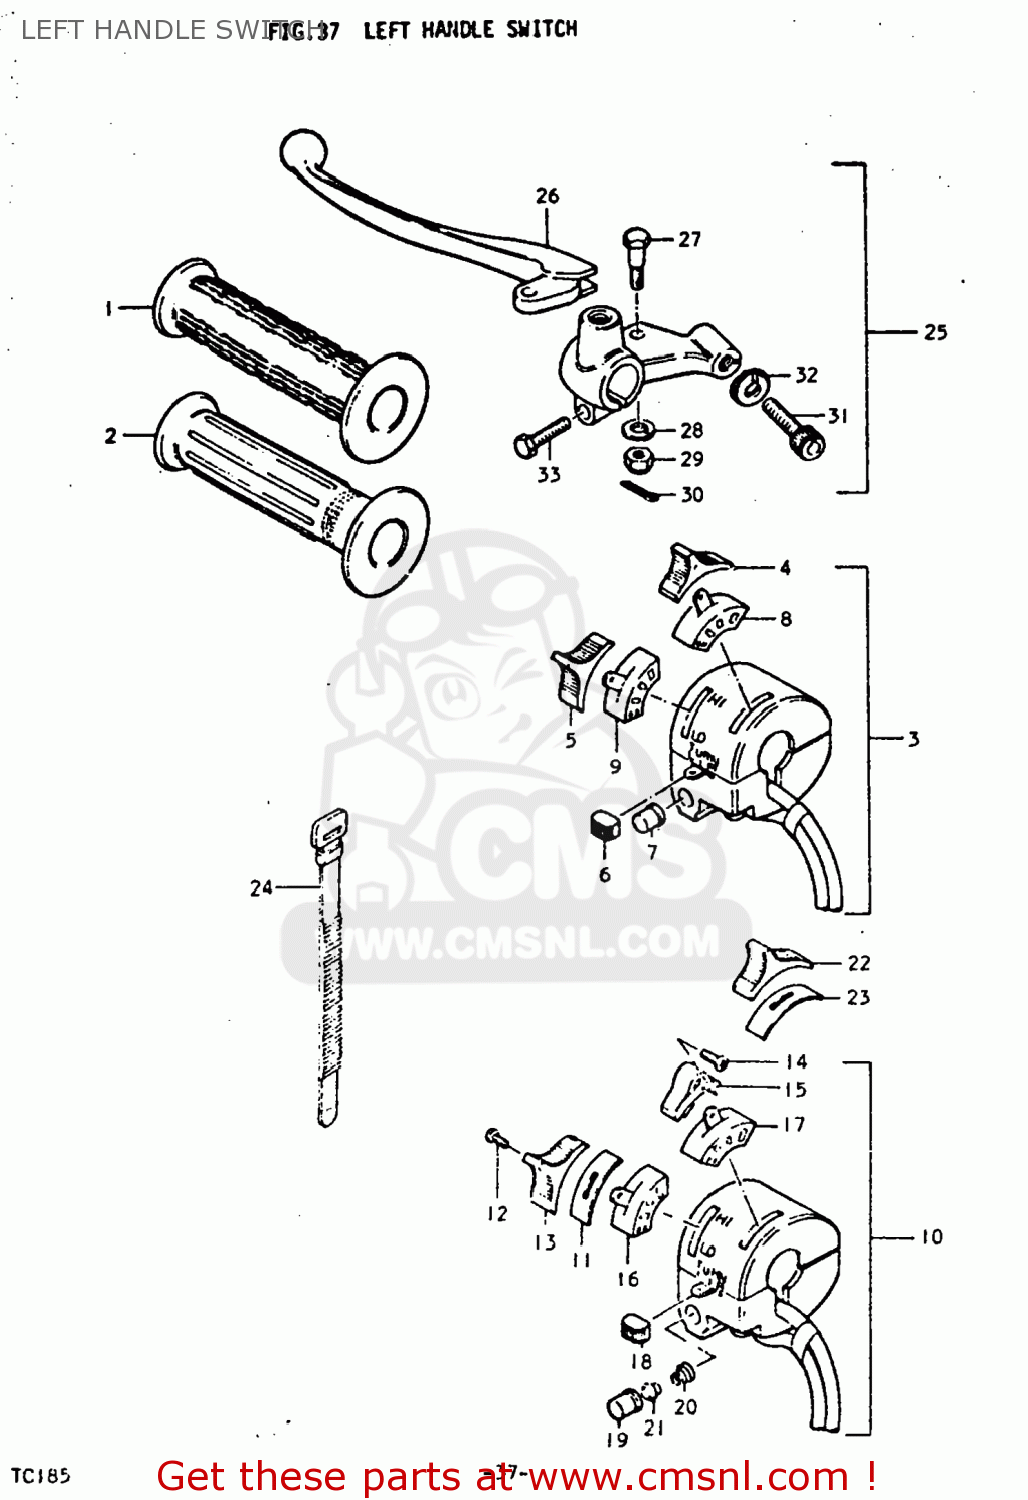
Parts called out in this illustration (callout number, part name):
1	GRIP
2	GRIP,L
3	SWITCH ASSEMBLY,HANDLE
4	KNOB,HANDLE SWITCH
5	KNOB,HANDLE SWITCH,UPPER
6	KNOB,HANDLE SWITCH
7	BUTTON, HORN
8	BLOCK, LIGHTING SWITCH SILDIN (L,ML,M)
9	SLIDING BLOCK, DIMMER SWITCH
10	SWITCH ASSEMBLY,HANDLE,LEFT
11	PLATE,DIMMER KNOB
12	SCREW, DIMMER
13	KNOB,HANDLE SWITCH,UPPER
14	SCREW
15	KNOB
16	SLIDING BLOCK, DIMMER SWITCH
17	BLOCK, LIGHTING
18	KNOB,HANDLE SWITCH
19	BUTTON, HORN
20	SPRING,BUTTON
21	PLATE,HORN BUTTON
22	KNOB,HANDLE SWITCH
23	PLATE,LIGHTING KNOB
24	CLAMP(L:120)
25	LEVER ASSEMBLY
26	LEVER,CLUTCH
27	BOLT,LEVER
28	LOCK WASHER
29	NUT,LEVER FITTNG
30	COTTER PIN
31	ADJUSTER,CABLE
32	NUT,CABLE ADJUSTER
33	BOLT
